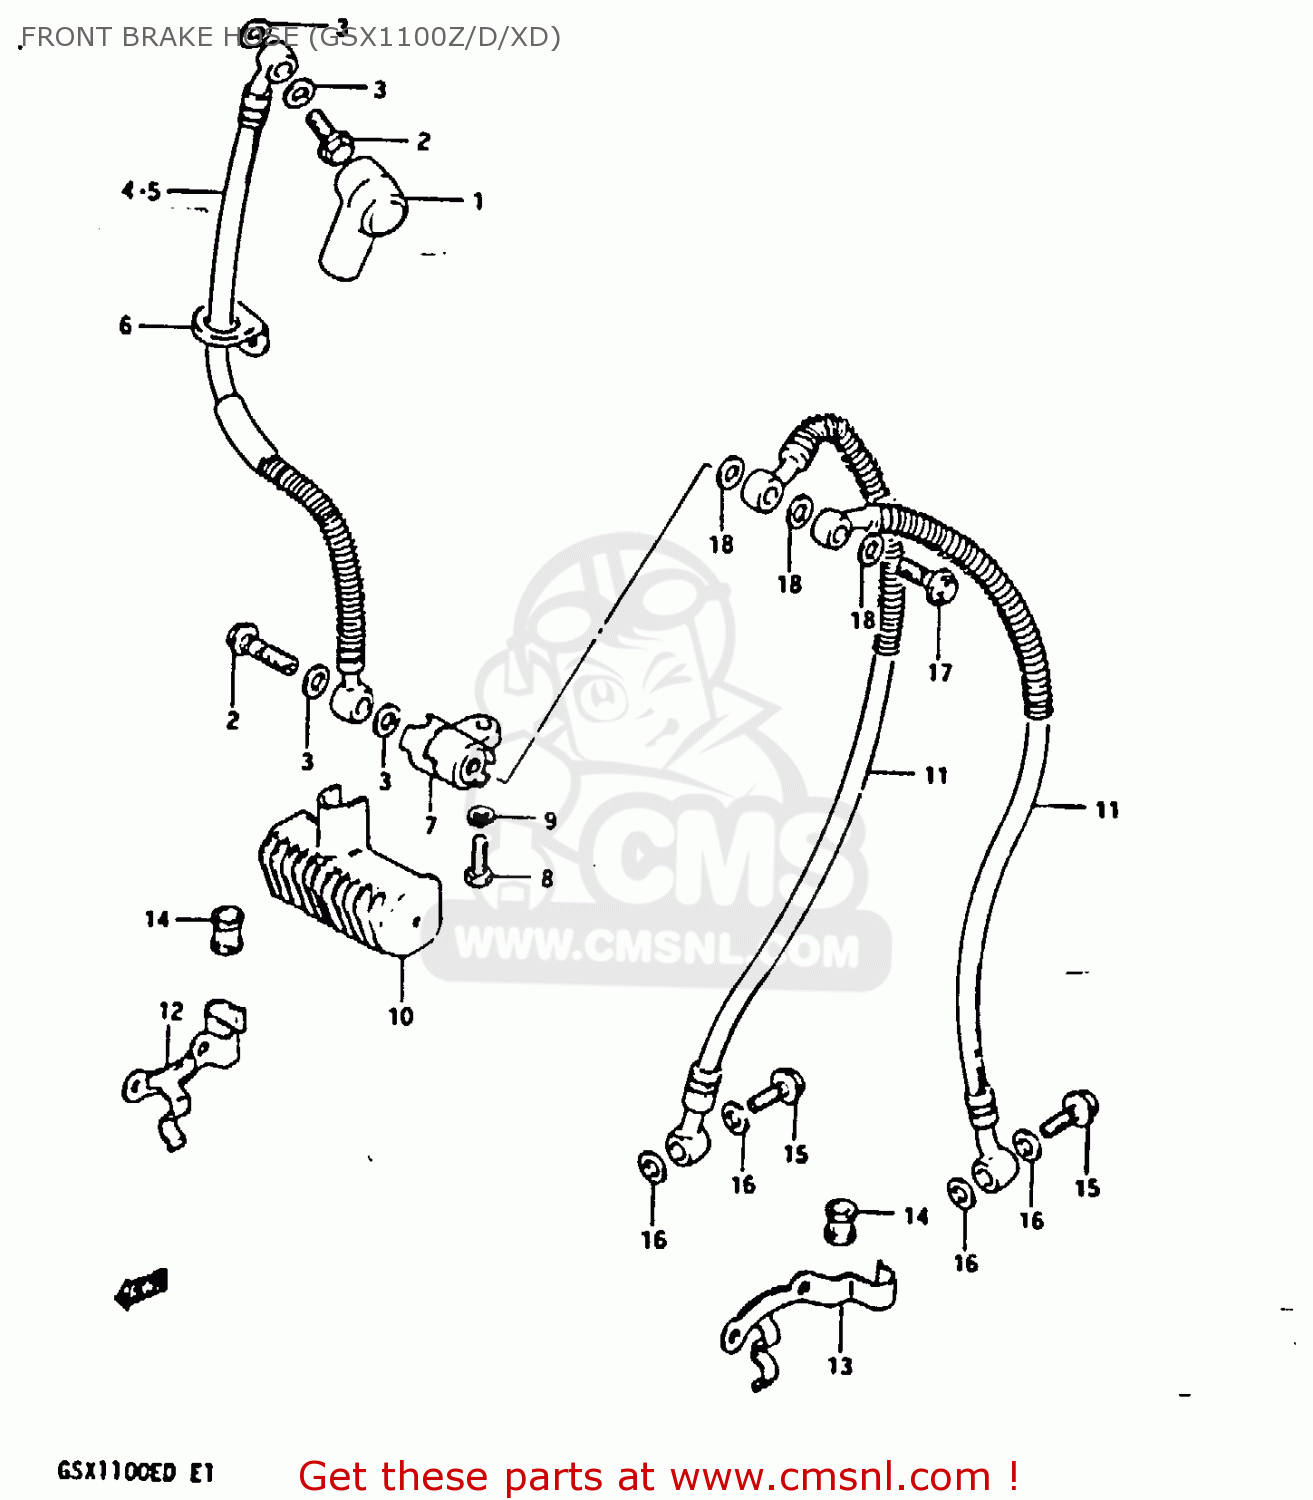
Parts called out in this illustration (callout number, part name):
1	BOOT,MASTER CYLINDER
2	BOLT,UNION
3	WASHER
4	HOSE,FRONT BRAKE
5	HOSE,FRONT BRAKE
6	GUIDE,BRAKE HOSE NO.1
7	JOINT,BRAKE HOSE
8	BOLT
9	LOCK WASHER
10	COVER,BRAKE HOSE JOINT
11	HOSE,FRONT BRAKE
12	CLAMP, HOSE RH
13	CLAMP,FRONT BRAKE HOSE
14	BUSH,BRAKE HOSE GUIDE,NO.2
15	BOLT,UNION
16	WASHER
17	BOLT,UNION
18	WASHER
